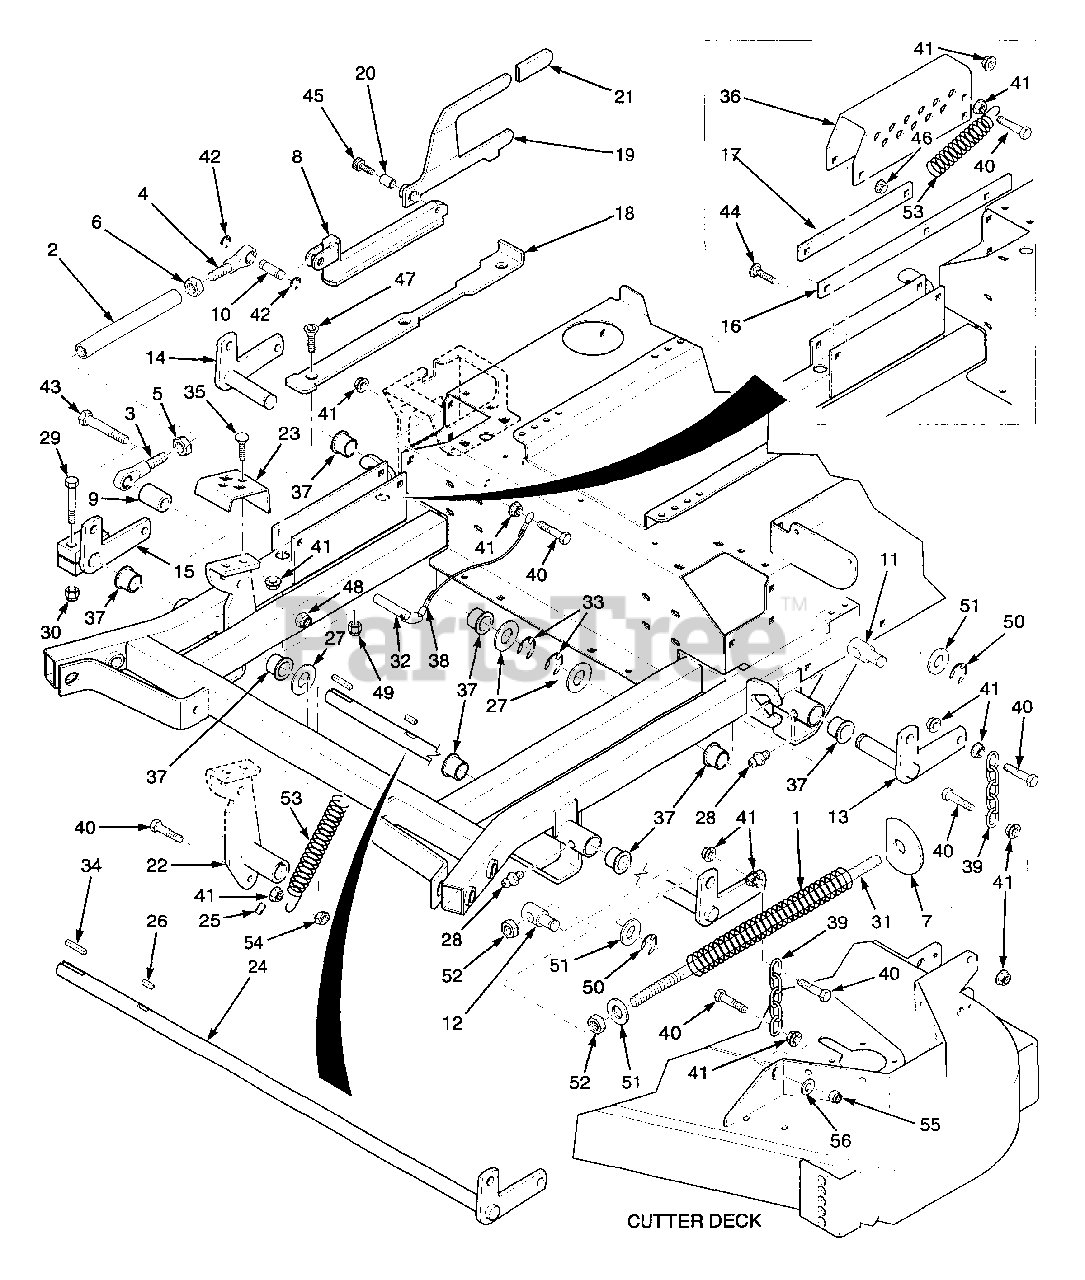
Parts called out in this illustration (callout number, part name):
1	Spring, Decklift
2	Rod, Decklift
3	Rod End, 1/2-20 Male RH
4	Rod End, 1/2-20 Male LH
5	Nut, Hex 1/2-20 RH
6	Nut, Hex 1/2-20 LH
7	Flatwasher, Spring Stop
8	Slide Weldment, Height Adjustment
9	Spacer, Decklift Pedal
10	Pin, Decklift
11	Swivel Joint, LH
12	Swivel Joint, RH
13	Bellcrank Weldment, LH Rear
14	Bellcrank Weldment, RH Rear
15	Bellcrank Weldment, RH Front
16	Guide, Short
17	Guide, Long
18	Lockplate, Decklift
19	Deck Latch
20	Bushing, .502 ID.
21	Grip, Deck Latch
22	Footplate Weldment, Decklift
23	Footplate, Height Adjustment
24	Bellcrank Weldment, LH Front
25	Set Screw, 5/16-18 x 1/2" Sq. Head
26	Key, 1/4 x 1/4 x 3-1/4"
27	Flatwasher, 1" (1.062 x 1.50 x .048)
28	Grease Fitting
29	Bolt, Hex Head 7/16-14 x 2-1/2"
30	Nut, Hex Elastic Stop 7/16-14
31	Stud, 5/8-11 x 22.0"
32	Ring Pin, 1/2 x 3.30"
33	Ring, Retaining 1" External "E"
34	Key, 1/4 x 1/4 x 1-1/4"
35	Bolt, Carriage 3/8-16 x 1-1/4"
36	Bracket, Cutting Height Adjustment
37	Bushing, 1.003 ID.
38	Lanyard, Deck Height Pin
39	Chain
40	Bolt, Hex Head 3/8-16 x 1-1/2"
41	Nut, Hex Serrated Flange 3/8-16
42	Ring, Retaining 1/2" External "E"
43	Bolt, Hex Head 1/2-13 x 3"
44	Bolt, Carriage 5/16-18 x 1"
45	Bolt, Shoulder 1/2 x 3/4"
46	Nut, Hex Serrated Flange 5/16-18
47	Screw, Cap 5/16-18 x 3" FHHS
48	Nut, Hex Elastic Stop 1/2-13
49	Nut, Hex Elastic Stop 5/16-18
50	Ring, Retaining 5/8" External "E"
51	Flatwasher, 5/8" (.656 x 1.312 x .095)
52	Nut, Hex 5/8-11
53	Spring, Helper
54	Locknut, 3/8-16 Center Lock
55	Nut, 3/8-16 Elastic Stop
56	Flatwasher, 3/8"
